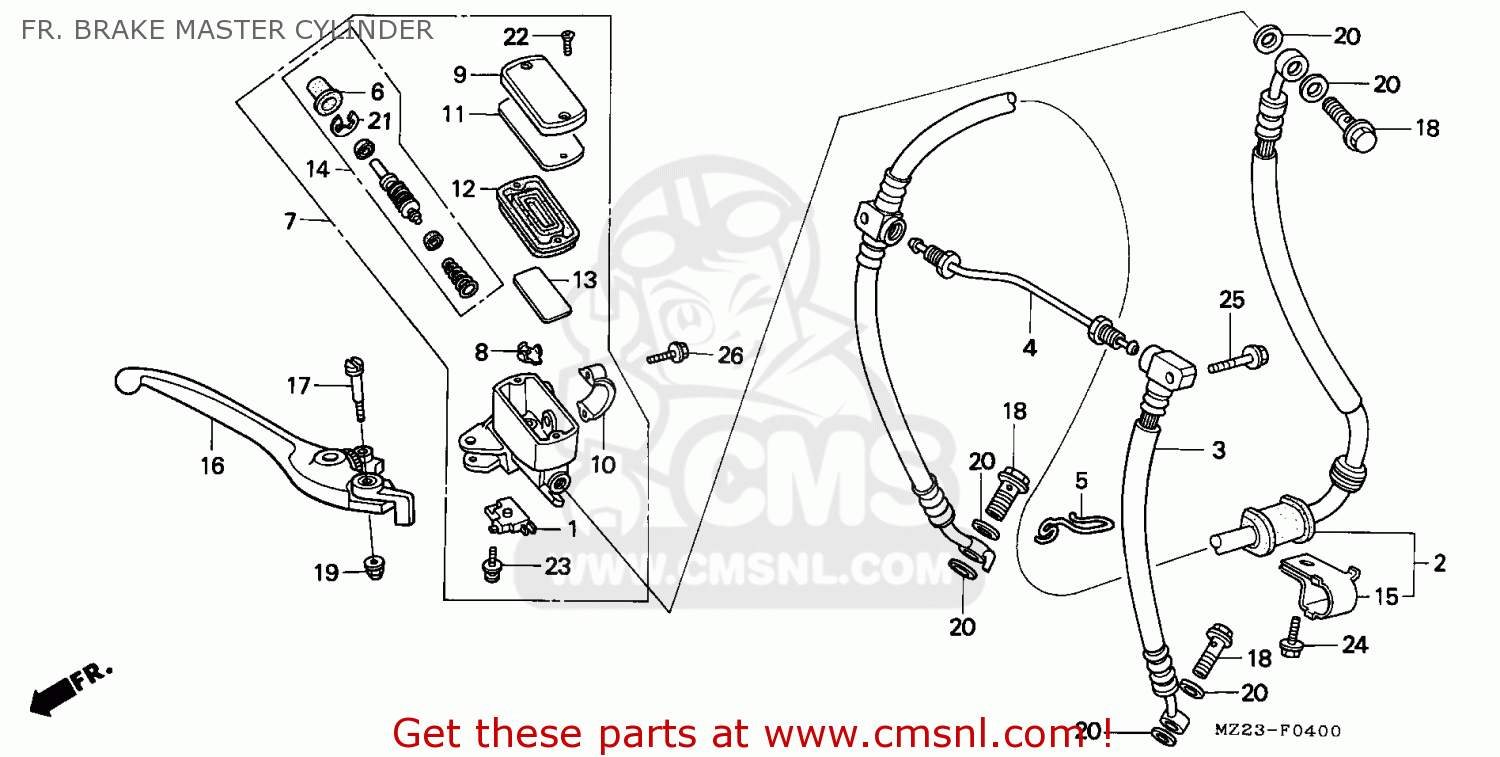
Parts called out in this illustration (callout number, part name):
1	SW ASSY,FR STOP
2	HOSE,R FR BRK MAI
3	HOSE,L FR BRK MAI
4	PIPE,FR BRK JOINT
5	CLAMPER,FR L HOSE
6	BOOT COMP.
7	SUB ASSY,FR M/C
8	PROTECTOR
9	CAP
10	HOLD,MAS.CYLINDER
11	PLATE,DIAPHRAGM
12	DIAPHRAGM
13	FLOAT,FR.MASTER C
14	CYLINDER SET,MAS
15	CLAMPER,BRAKE HOS
16	LEVER ASSY.,R.HAN
17	BOLT,HNDL PIVOT
18	BOLT,OIL,10X22
19	NUT,CAP,6MM
21	CIRCLIP
22	SCREW,FLAT,4X12
23	SCREW WASH.,4X12
24	BOLT,FLANGE,6X12
25	BOLT,FLANGE,6X25
26	BOLT,FLANGE,6X22
